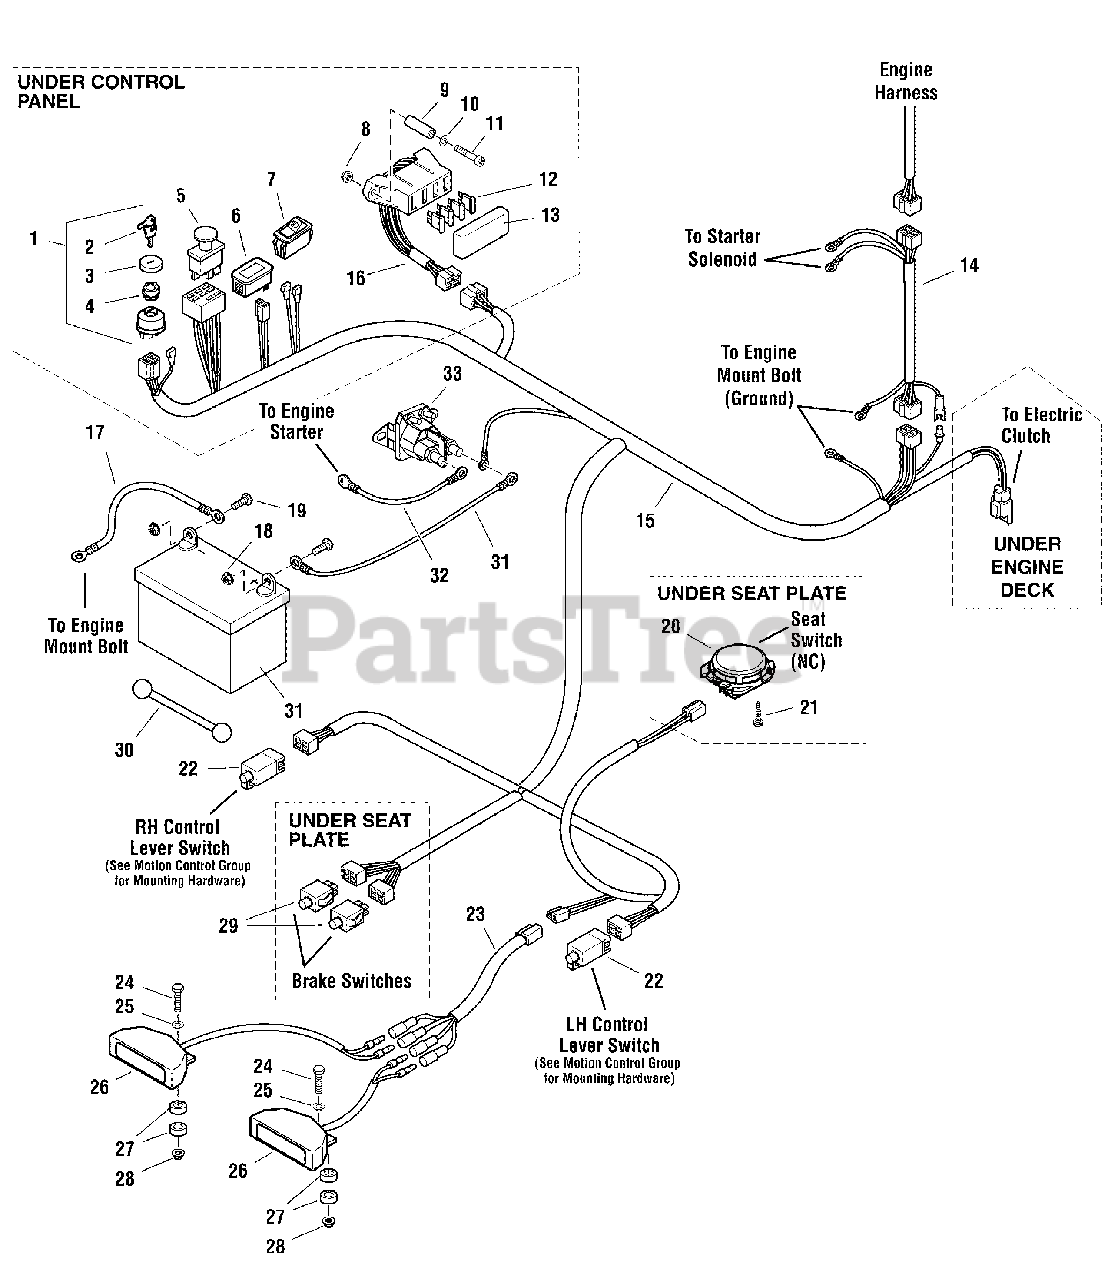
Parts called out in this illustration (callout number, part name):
1	SWITCH ASMY-IGNITION INDAK NO KEYS
2	KEYS. BLISTER PK KIDS+MWRS DON'T MIX
3	COVER, PLASTIC, SNAP ON
4	PLASTIC NUT
5	SWITCH, PTO
6	HOUR METER
7	HEADLIGHT SWITCH
8	NUT, #10-24 Hex Nylon Lock
9	SPACER, .20 x .38 x 1.25
10	WASHER, #10 SAE
11	SCREW, #10-24 x 2"
12	FUSE, 20A
13	FUSE BLOCK COVER
14	WIRE HARNESS, BRIGGS JUMPER - IS2000Z
14	WIRE HARNESS, JUMPER KAW FS
15	WIRE HARNESS, MAIN, IS1500ZX
16	WIRE HARNESS, FUSE BLOCK - IS2000
17	BATTERY CABLE, NEGATIVE, 10
17	BATTERY CABLE, NEGATIVE, 14
18	NUT, 1/4-20 Hex Serrated Flange
19	BOLT, 1/4-20 x 3/4
20	SWITCH, Seat, Gray, NC (BOLT-IN)
20	SWITCH, Seat, Gray, NC (TWIST-IN)
21	BOLT, Hex Washer Head PLASTITE, 1/4 X 1/2
22	SWITCH, PLUNGER, N.O./N.C.
23	HEADLIGHT HARNESS
24	BOLT, 1/4-20 X 1-3/4
25	WASHER, 1/4 SAE (5025154)
26	HEADLIGHT
27	SPACER, .39 X .75 X .38
28	NUT, 1/4-20 HEX NYLOCK FLANGE (5025391)
29	SWITCH, DP NO/NC SNAP-IN
30	STRAP, BATTERY, 14 LONG, Rubber
31	BATTERY CABLE, POSITIVE, 15
32	BATTERY CABLE, POSITIVE, 8
33	SOLENOID-4 POLE 12 VOLT DC (TROMBETTA)
